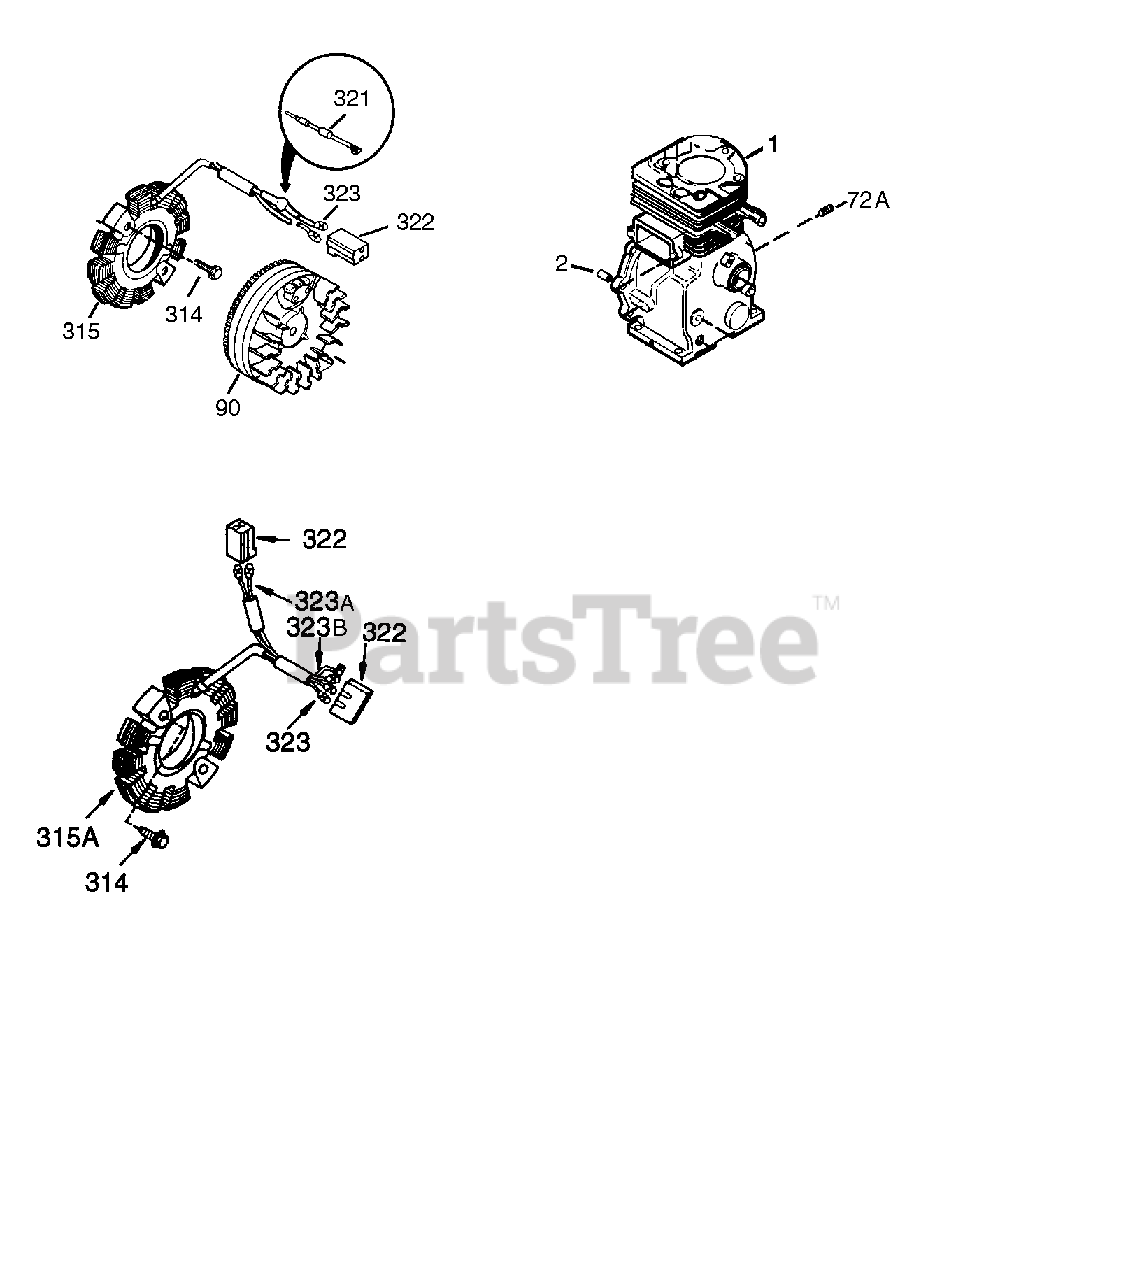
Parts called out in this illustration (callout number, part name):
1	"Cylinder (Incl. 2, 20, 72 & 72A) (3-1 /8" Bore)
2	Dowel Pin
72A	Oil Drain Plug (Internal Hex., 1/4-18 )
90	Flywheel (3 Amp, W/Ring Gear)
178	Nut & Lock Washer 1/4-28
213	Screw, 10-24 X 29/32"
216	R.P.M. Adjusting Lever
277A	Screw, 5/16-18 X 4-1/2" (Muffler Shou lder Screw)
280B	Baffle - Air Restrictor
293A	Screw, T-30, 1/4-20 X 27-32"
300A	Fuel Tank (Incl. 292 & 301) (4-Qt.) ( Premium Style)
309	Screw, 10-32 X 5/16"
314	Screw, 1/4-20 X 3/4"
322	Connector Body (single pin)
323	Terminal (single pin)
329A	Screw, 8-32 X 23/64"
342A	Screw, 5/16-18 X 7/8"
351A	Primer Line
704	Screw, 1/4-20 X 5/8"
999	Winter Maintenance Kit includes 32 oz . - SAE5W30 Oil, spark plug, switch k ey, fuel stabilizer
999	Winter Maintenance Kit includes 32 oz . - SAE0W30 Synthetic Oil, spark plug , switch key, fuel stabilizer
